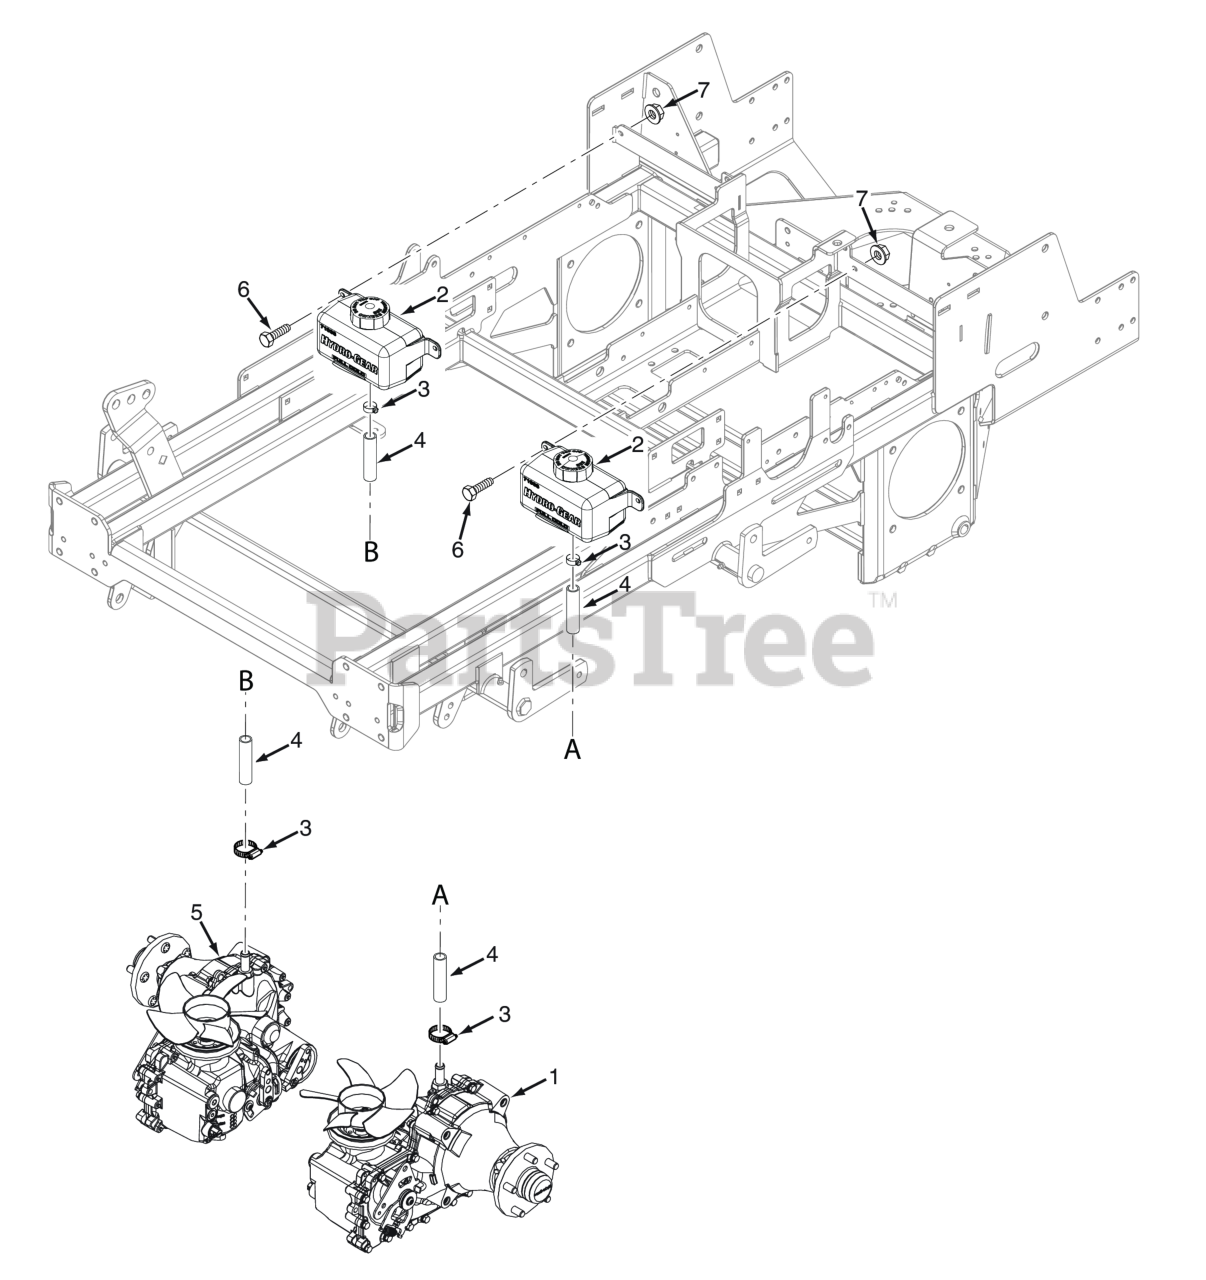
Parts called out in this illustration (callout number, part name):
1	Transaxle, LH
2	Hydraulic Tank, 1,000 ml
3	Clamp, 1" Max Dia.
4	HOSE 5/8 ID PUSH ON RUBBER CVD
5	Transaxle, RH
6	BOLT, HEX HEAD, 1/4-20 X 3/4 GR.5
7	NUT, 1/4-20 SERRATED FLANGE HEX HEAD
